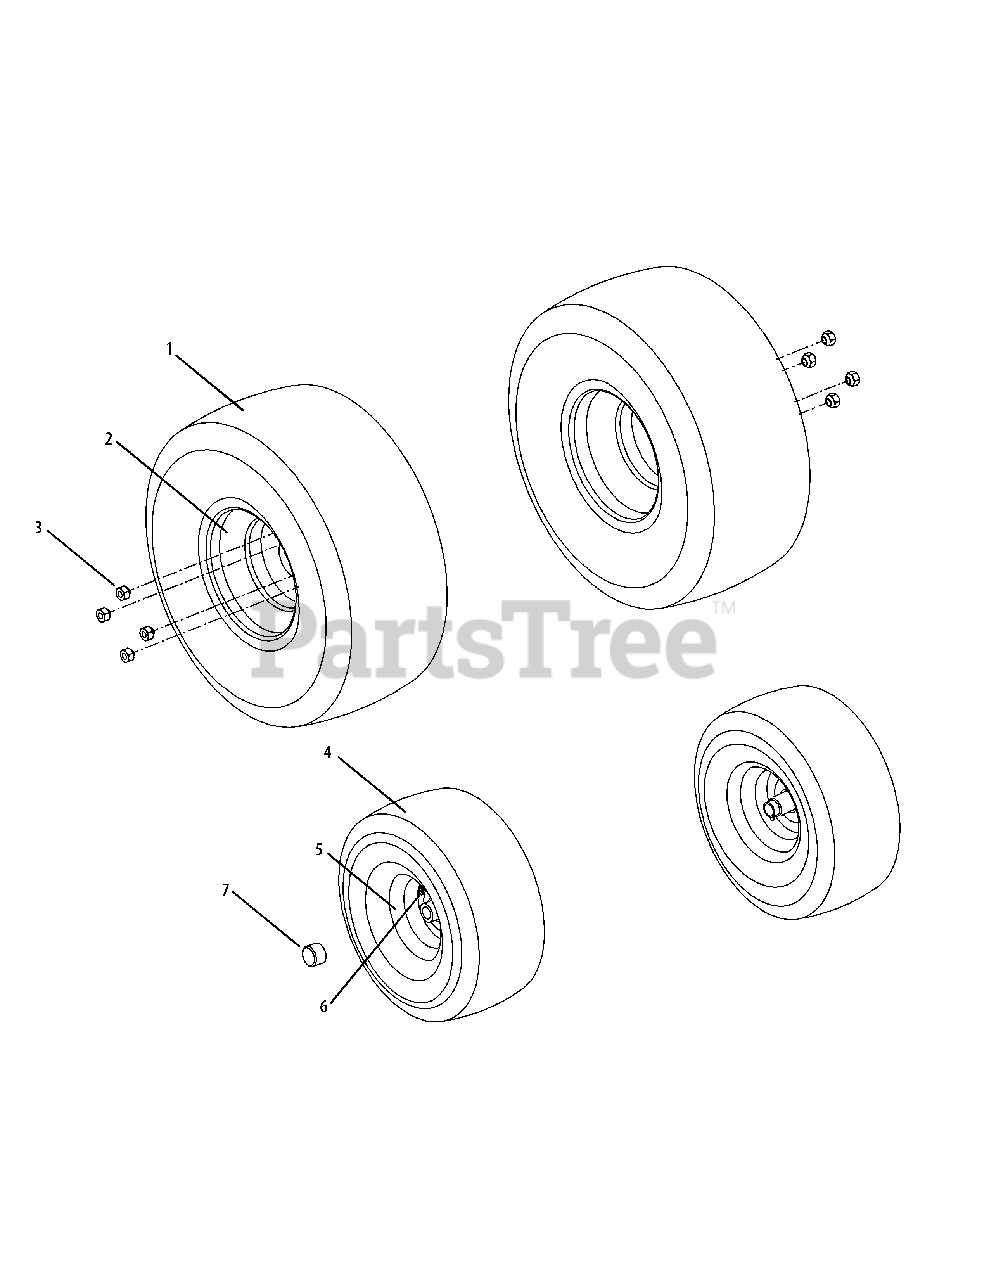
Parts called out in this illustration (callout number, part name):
1	Tire, 23 x 10.5 x 12 Square Shoulder
2	Rim Assembly, 12.0 x 7.0 (4-Lug)
3	Lug Nut, 7/16-14
4	Tire, 16 x 7.5 x 8 Square Shoulder
5	Rim Assembly, 8 x 5.38
6	Valve, Tubeless Air
